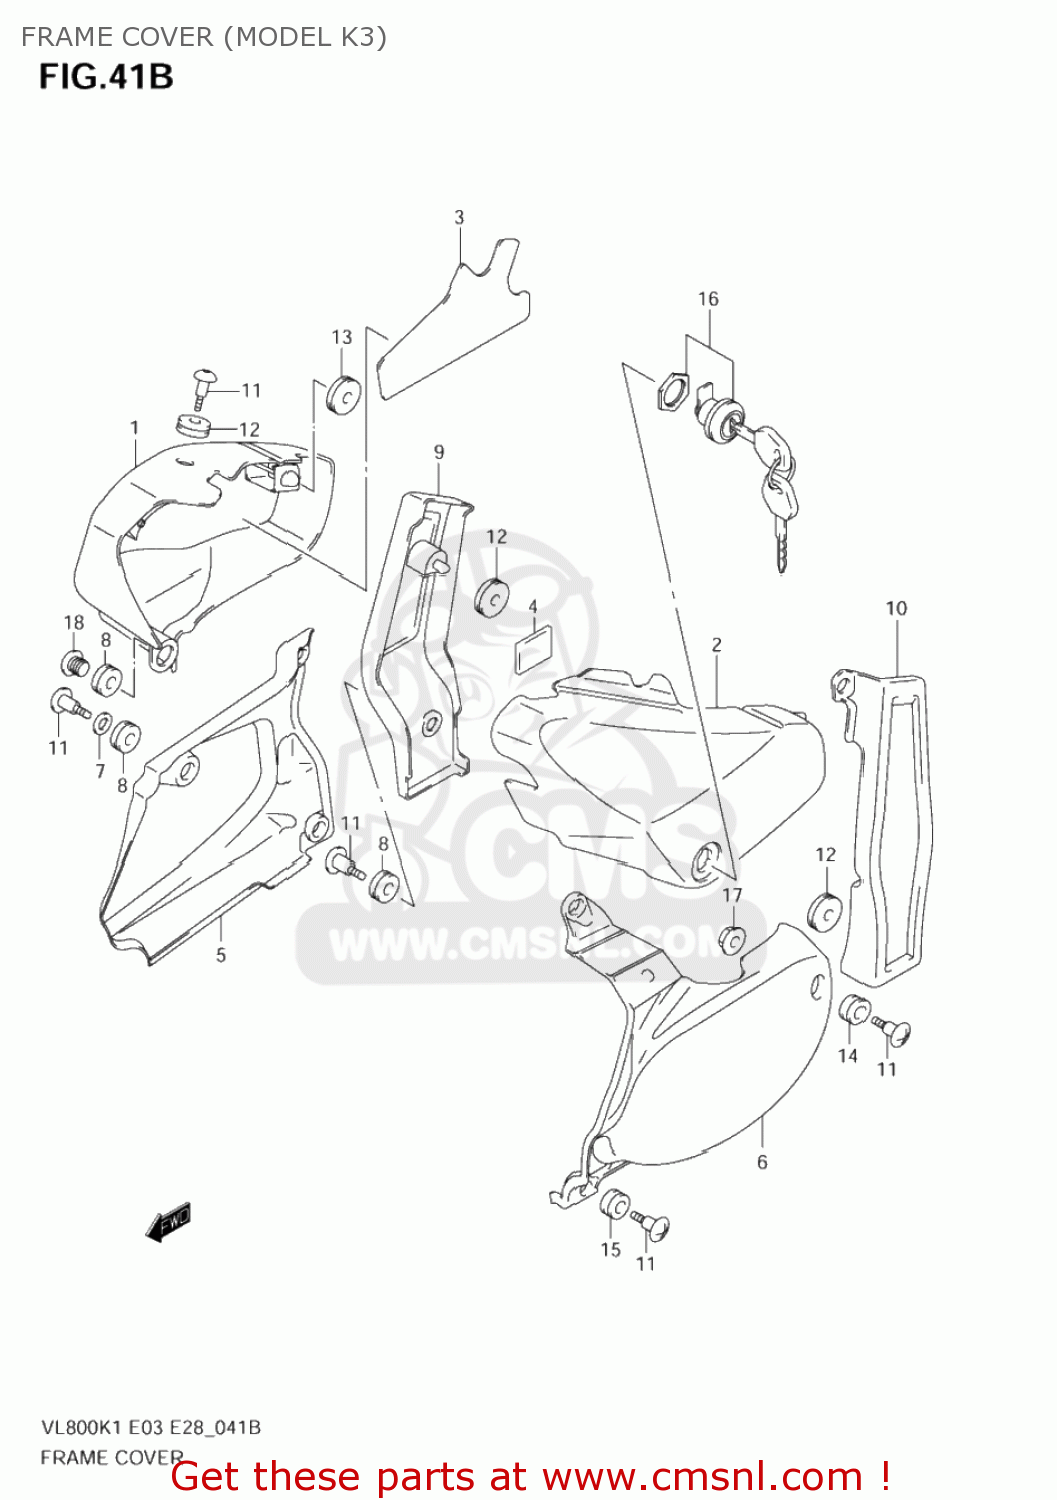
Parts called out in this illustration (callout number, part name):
1	COVER,SIDE,R(GREEN)
2	COVER,SIDE,L(S
3	SHIELD,FRAME COVER
4	PAD,BALANCER UPPER,R
5	COVER,SIDE LWR,R
6	COVER,SIDE LWR,L
7	WASHER(10.5X20X2.3)
8	CUSHION
9	COVER SIDE,REA
10	COVER,SIDE RR,L
11	SCREW(6X20)
12	CUSHION
13	CUSHION
14	CUSHION
15	CUSHION
16	LOCK SET,COVER
17	NUT
18	CAP(OD:14)
